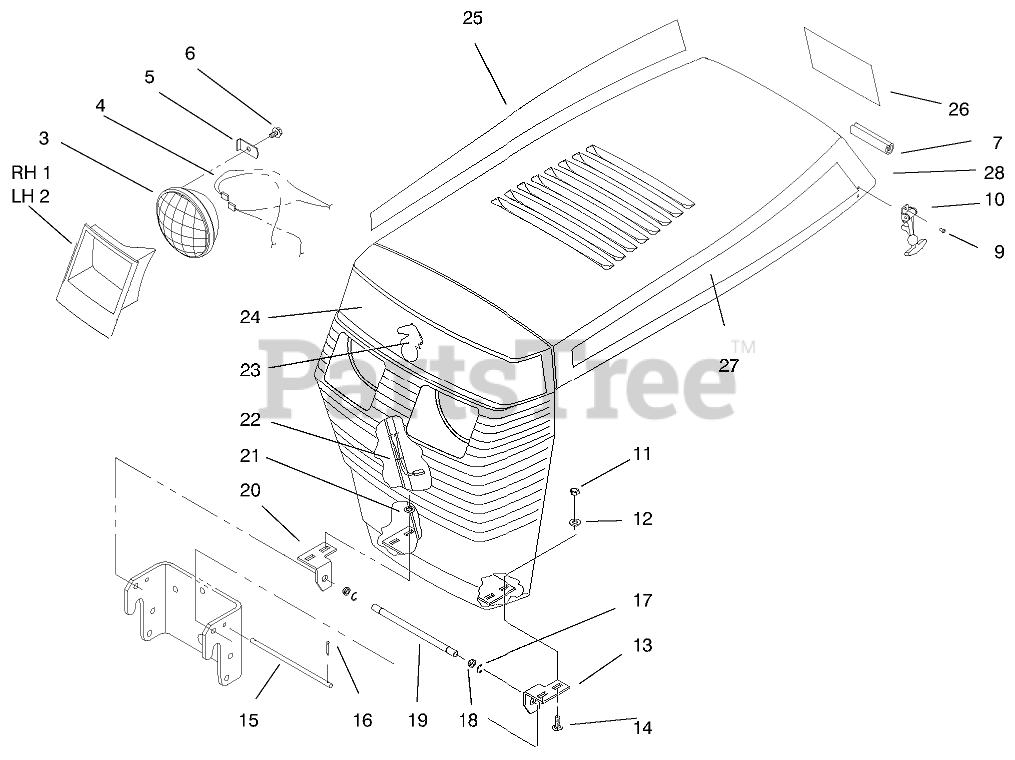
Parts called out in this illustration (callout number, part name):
1	BEZEL-HEADLIGHT, LH
2	BEZEL-HEADLIGHT, RH
3	HEADLAMP
4	HARNESS-HEADLIGHT
5	LOCK-HEADLIGHT
6	SCREW-HWH
7	EDGING-CONSOLE
8	SCREW-HH
9	RIVET-POP
10	HANDLE ASM
11	NUT-LOCK, NI
12	WASHER-FLAT
13	BRACKET-GRILL, LH
14	SCREW-CARR
15	ROD-HOOD STOP
15	Bracket-Brake
17	BUSHING-NYLINER
18	RING-RETAINING
19	ROD-GRILL PIVOT
20	BRACKET-GRILL, R H
21	WASHER-LOCK, INTERNAL
22	TIE-CABLE
23	LOGO - HORSEHEAD
24	DECAL-FRONT HOOD, TOP
25	DECAL - RH HOOD TOP
26	DECAL - DANGER
27	DECAL - LH HOOD TOP
28	Hood
